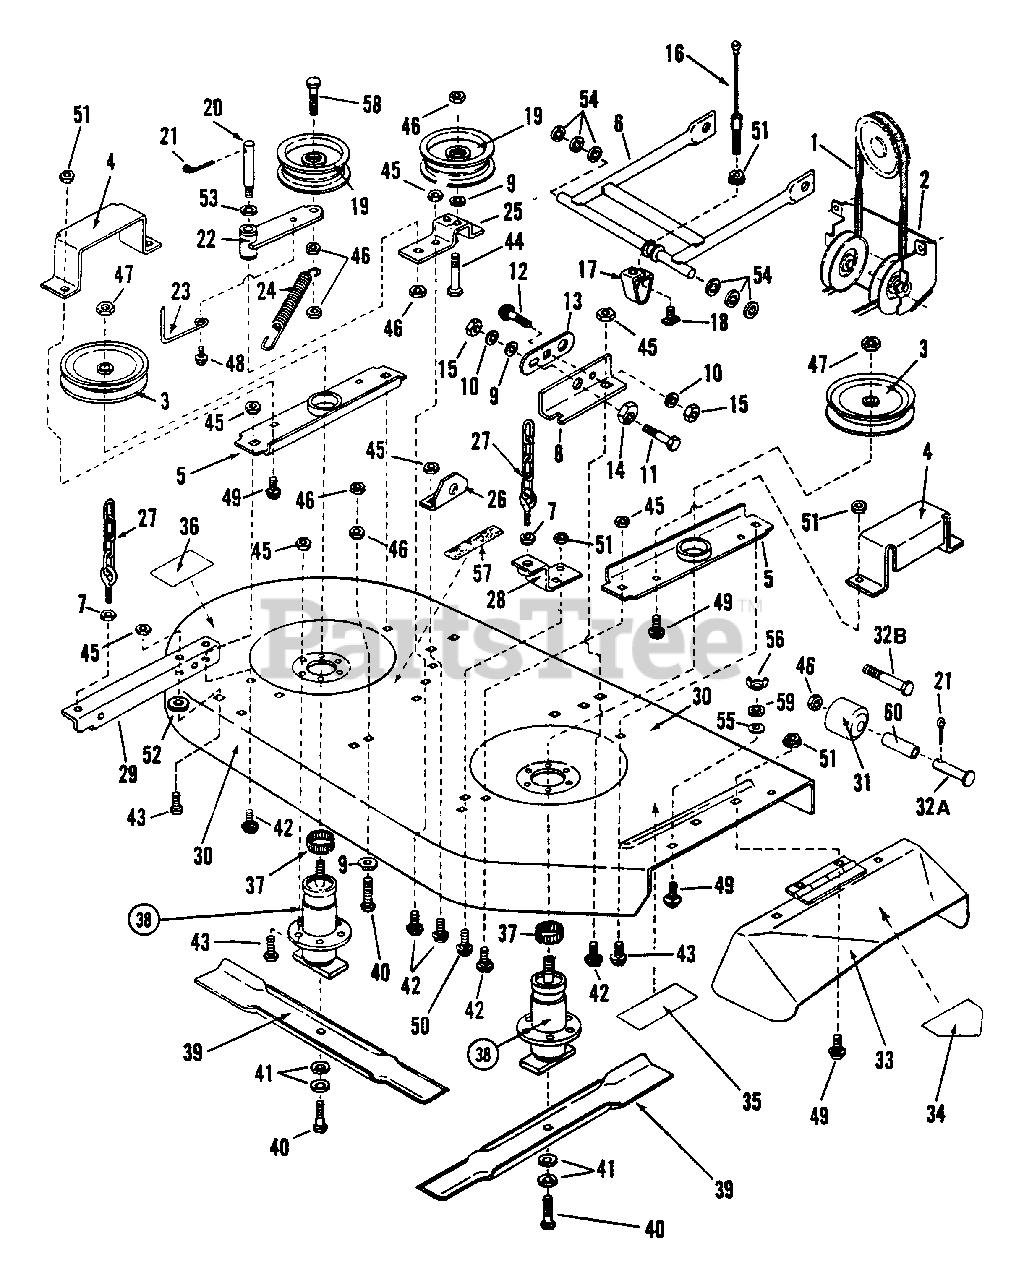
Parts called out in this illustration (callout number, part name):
1	BELT, 41" Mower (A137)
2	ASSEMBLY, Mule Drive
3	PULLEY, 5-3/4" O.D.
4	GUARD, Pulley
5	BRACE, Spindle
6	ASY, Front Lift Arm
7	JAM-NUT, 3/8-16 Hex
8	BRACKET, Right Front
9	WASHER, 3/8" Flat
10	WASHER, 3/8 Split Lock
11	SCREW, 3/8-16 x 1" Hex Head
12	BOLT, 3/8-16 x 3/4" Square Neck Carriage, Grade 5
13	LINK, Adjustment
14	RING, Adjustment
15	NUT, 3/8-16 Hex
16	CABLE, Front Lift, 8"
17	BRACKET, Fr. Lift Arm Hanger
18	T-NUT, 5/16-18
19	PULLEY, 4.1 O.D.
20	STUD, Idler (3/8-24)
21	COTTER-PIN, 1/8 x 1"
22	ASY, Idler Arm
23	GUIDE, Belt
24	SPRING, Idler Arm
25	BRACKET, Idler
26	BRACKET, Front Left Hanger
27	ASY, 3/8 Bolt/Chain
28	BRKT, Rear Rt. Supp.
29	BRKT, Rear Left Supp.
30	MOWER DECK, 41"
31	WHEEL, GAGE
32A	PIN, 1/2 O.D. x 1.75
32B	SCREW, 3/8-24 x 3-3/4" Hex Head Cap, Grade 5
33	DEFLECTOR, (Side Chute)
34	DECAL, Danger (Cut Finger)
35	DECAL, Caution (Deflector)
36	DECAL, Caution (Rot. Blades)
37	RING, Tolerance, 3/4"
38	ASY, Spindle
39	BLADE, 21" Cutter
40	SCREW, 3/8-24 x 1-1/4" Hex Head Cap, Grade 5
41	CONE-WASHER
42	BOLT, 3/8-16 x 3/4" Square Neck Carriage, Grade 2
43	BOLT, 3/8-16 x 3/4" HFL
44	SCREW, 3/8-24 x 1-3/4" Hex Head cap, Grade 5
45	NUT, 3/8-16 Hex Fl. Lock
46	NUT, 3/8-24 Hex Ctr. Lk.
47	NUT, 3/4-16 Jam Lock
48	SCREW, 1/4-20 x 5/8" HWST
49	BOLT, 5/16-18 x 5/8 Square Neck Carriage, Grade 5
50	BOLT, 5/16-18 x 1/2" Hex Flange Lock, Grade 5
51	NUT, 5/16-18 Hex Flange Lock, Grade 5
52	WASHER, 7/16 SAE
53	WASHER, 5/8 Flat
54	WASHER, Spacer
55	RETAINER, 5/16 Bolt
56	WING-NUT, 5/16-18
58	SCREW, 3/8-24 x 2" Hex Head Cap, Grade 5
59	WASHER, 5/16 Split Lock
60	SPACER
